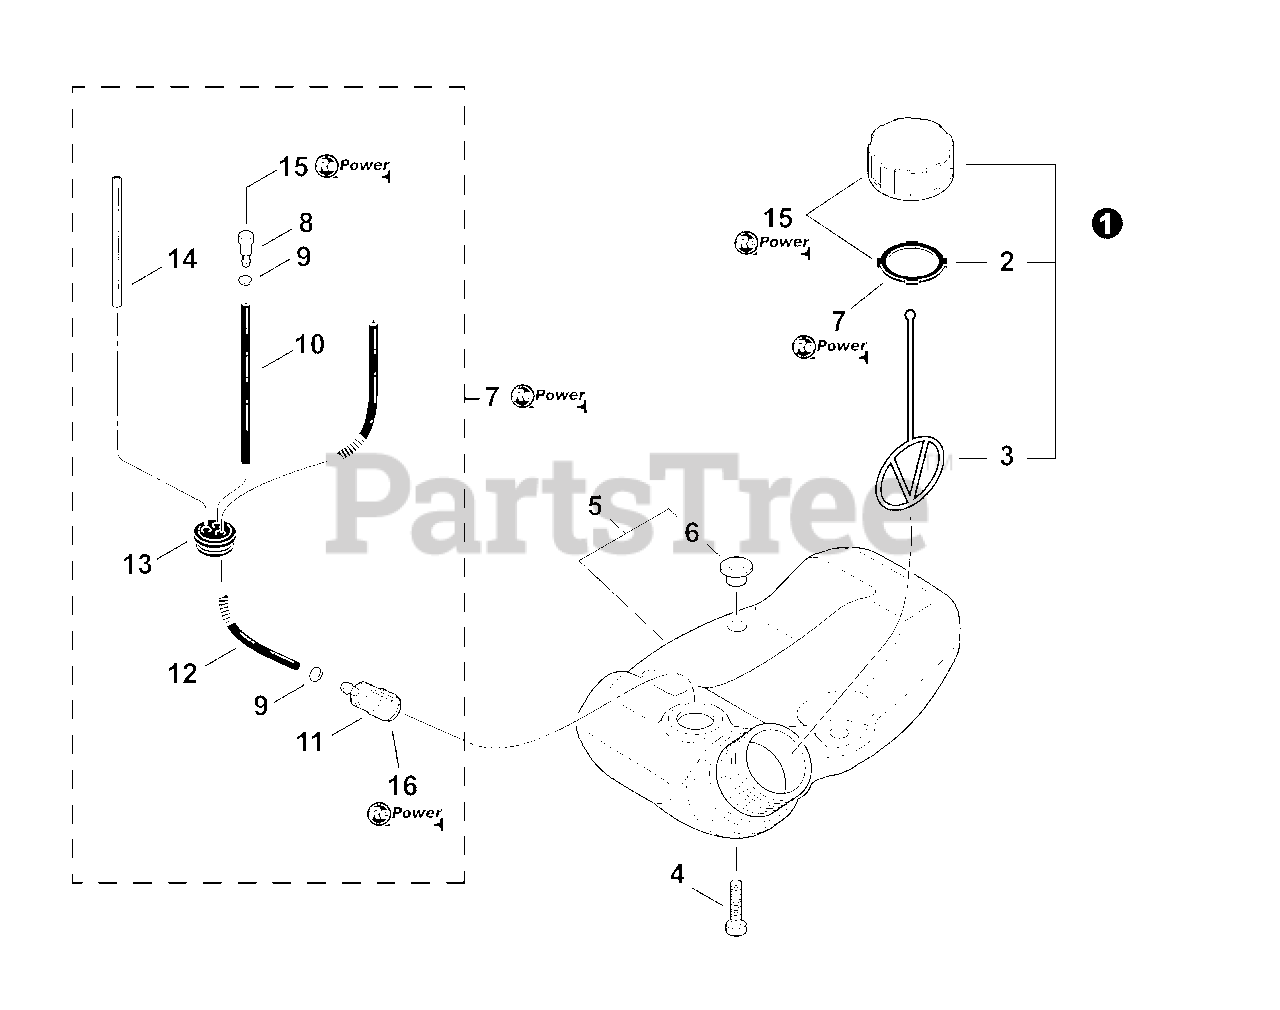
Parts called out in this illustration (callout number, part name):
1	CAP ASSY, FUEL
2	GASKET, FUEL CAP
3	CONNECTOR, CAP L= 123
4	BOLT, TORX 5×20
5	TANK ASSY, FUEL
6	COLLAR 5
7	FUEL SYSTEM KIT
8	VENT ASSY
9	CLIP 6 MM
10	PIPE, FUEL 3×6×80 CLEAR
11	FILTER, FUEL
12	PIPE, FUEL 3×5×210 BLACK
13	GROMMET, FUEL
14	PIPE, FUEL 3×5×90 BLACK
15	CAP/VENT KIT - REPOWER
16	FILTER KIT - REPOWER
16	TUNE-UP KIT - REPOWER
